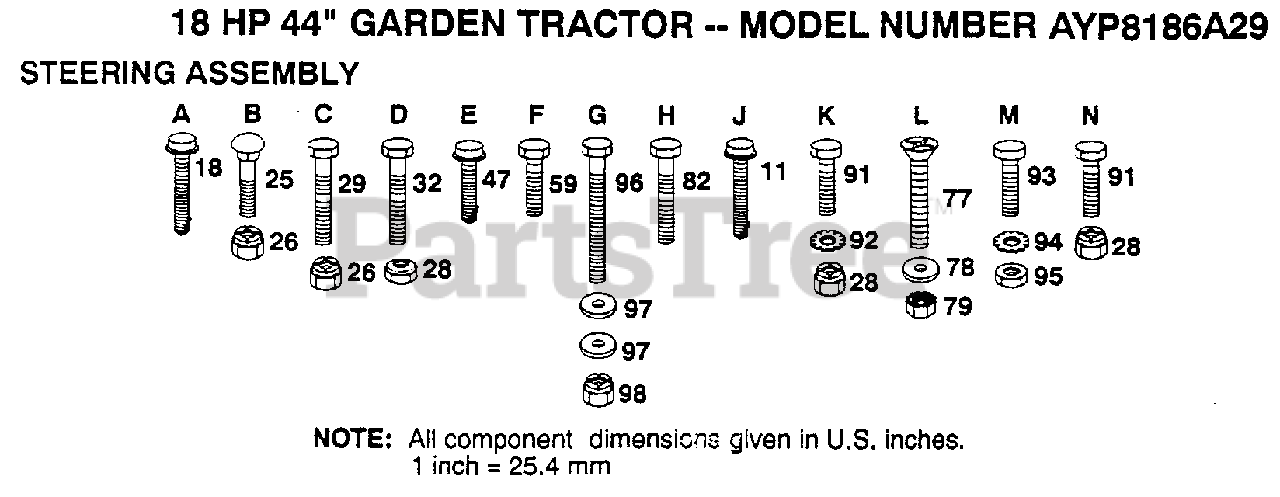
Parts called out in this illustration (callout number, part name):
11	SCREW LT
18	SCREW
25	SCREW
29	BOLT
47	SCREW LT
77	SCREW
78	WASHER
82	SCREW SPECIAL
92	LOCKWASHER
93	BOLT
